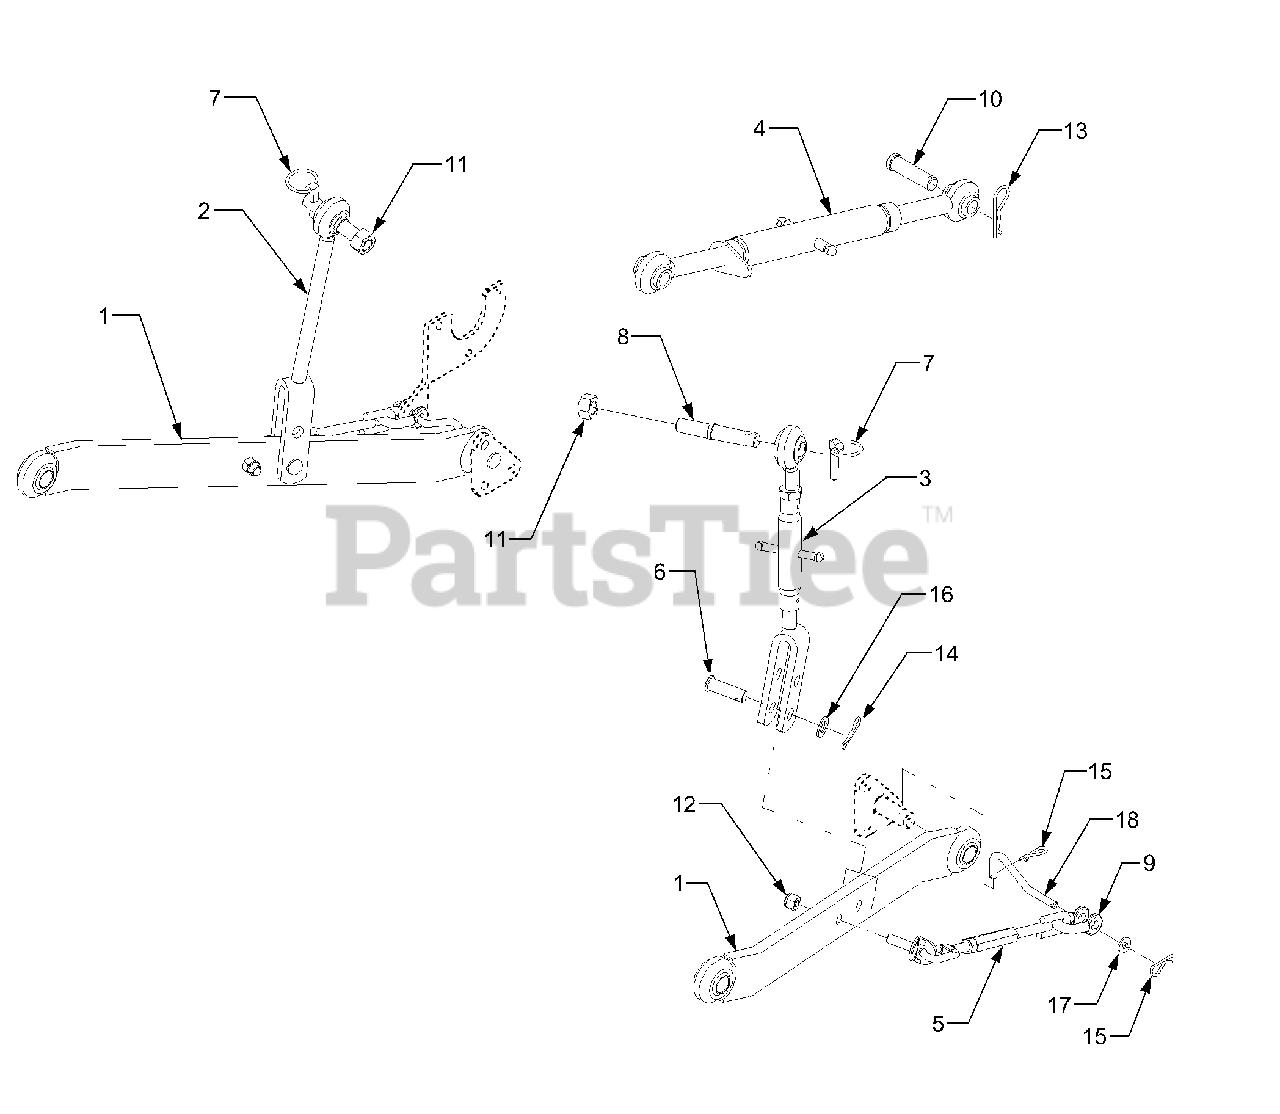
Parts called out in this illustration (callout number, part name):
3	Link, Lift - Adjustable
4	Link, Upper Center
5	Chain Assembly, Check
6	Pin, Clevis, .624 Dia.
7	Pin, Klik, 1.75 Lg.
8	Pin, Upper Lift Arm
9	"U" Clevis, Check Chain
10	Pin, Clevis, .75 x 2.75
11	Nut, Hex, 3/4-16 GR8
12	Nut, Hex Insert Lock, 1/2-20
13	Pin, Internal Cotter, .148 x 3.0
14	Pin, Internal Cotter, .125 x 1.75
15	Pin, Internal Cotter
16	Washer, Flat, .635 x 1.12 x .09
17	Washer, Flat, .385 x .87 x .09
18	Pin, Double Clevis
